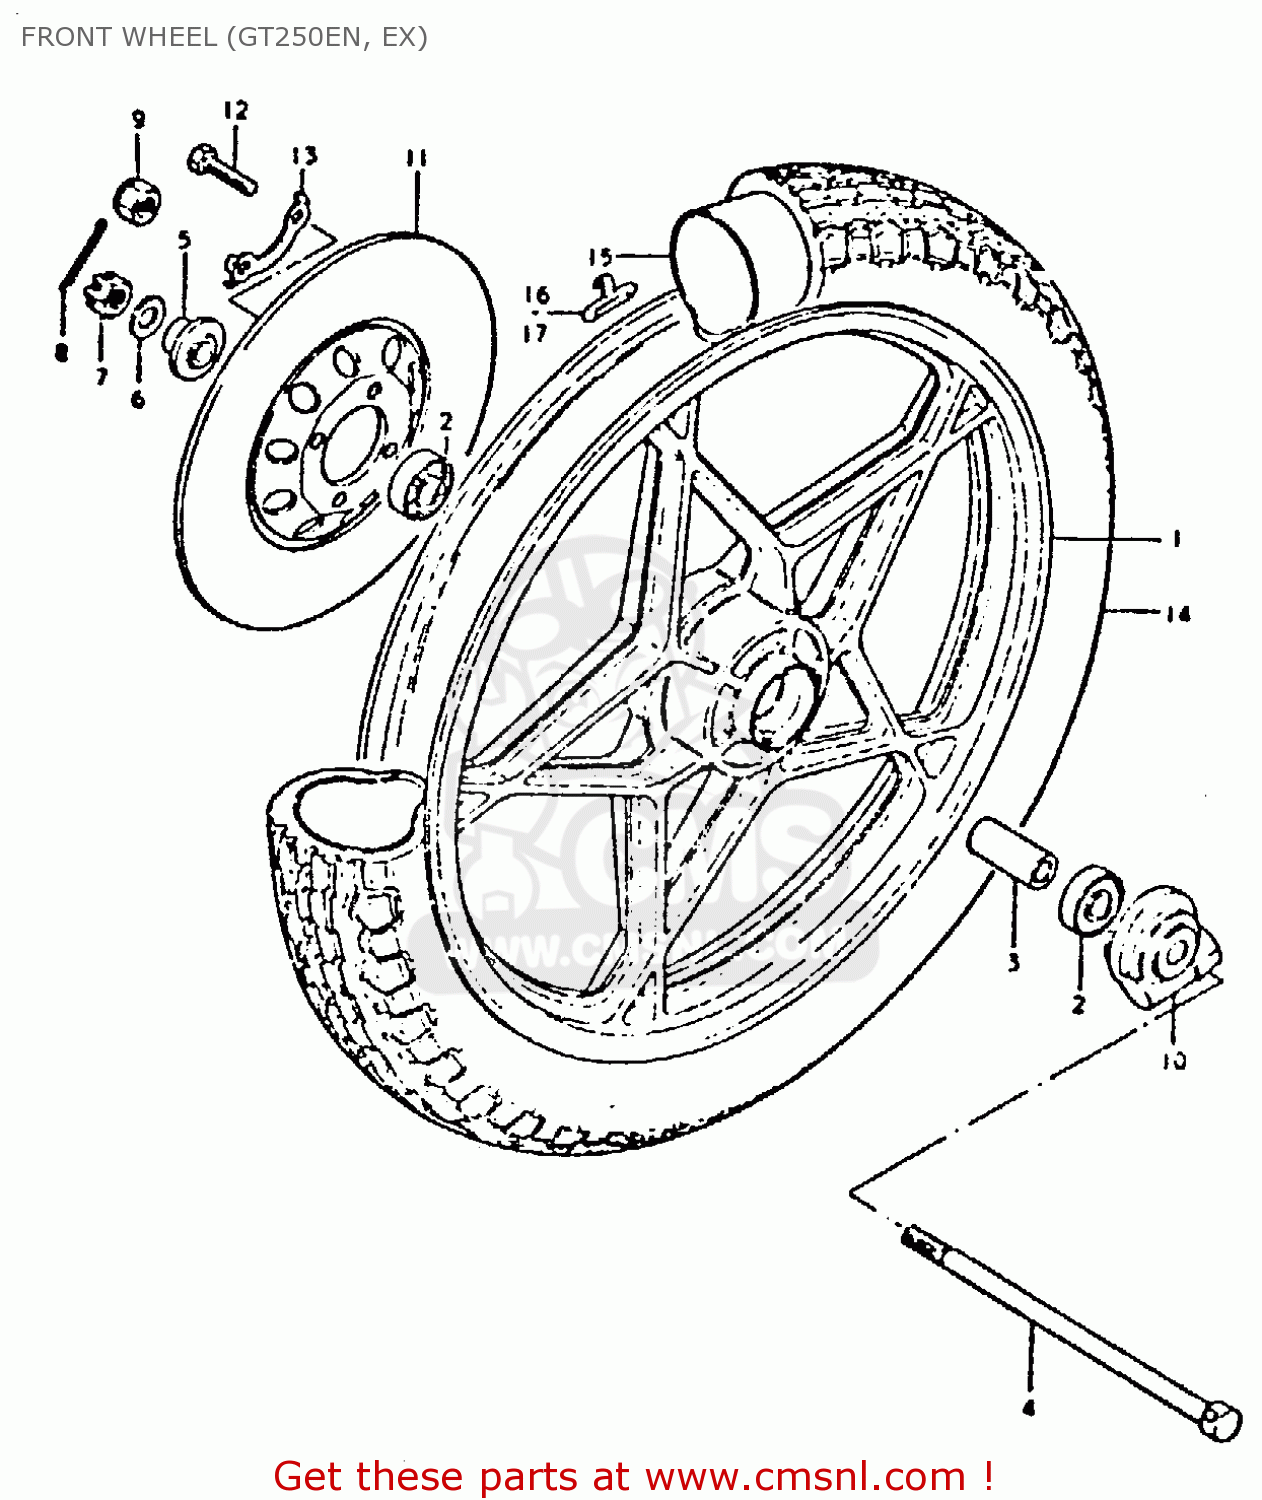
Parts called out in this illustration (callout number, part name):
1	WHEEL, FRONT
2	BEARING
3	SPACER (12.6X19X52)
4	AXLE, FRONT
5	SPACER,FR AXLE,L
6	WASHER
7	NUT 12MM
8	COTTER PIN
10	BOX ASSY,SPEEDOMETER GEAR
11	DISC,BRAKE
12	BOLT(8X25)
13	WASHER
14	TIRE,FRONT
15	TUBE,INNER
16	BALANCER,WHEEL
17	BALANCER,WHEEL
